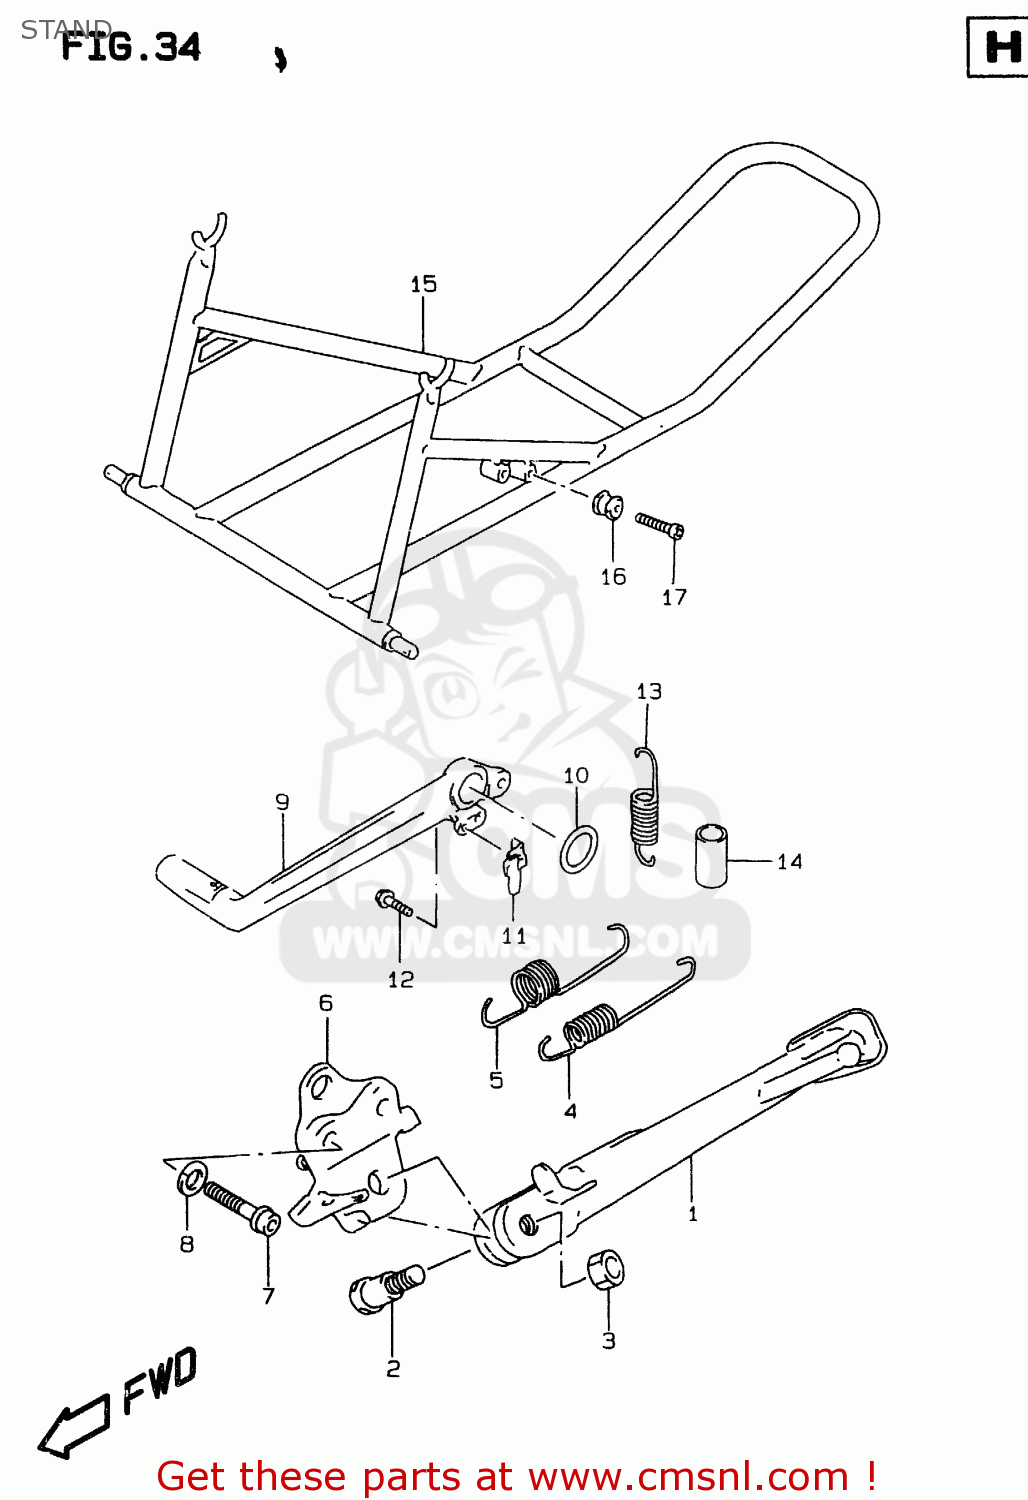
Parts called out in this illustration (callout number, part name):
1	STAND,PROP
2	BOLT(10X34)
3	NUT
4	SPRING
5	SPRING
6	BRACKET,PROP STAND
7	BOLT
8	LOCK WASHER
9	PEDAL,BRAKE
10	WASHER(18X24X1)
11	HOOK,RETURN SPRING
12	SCREW
13	SPRING
14	TUBE,BRAKE SPRING GUIDE
15	STAND ASSEMBLY,REAR
16	HOLDER,STAND
17	BOLT
